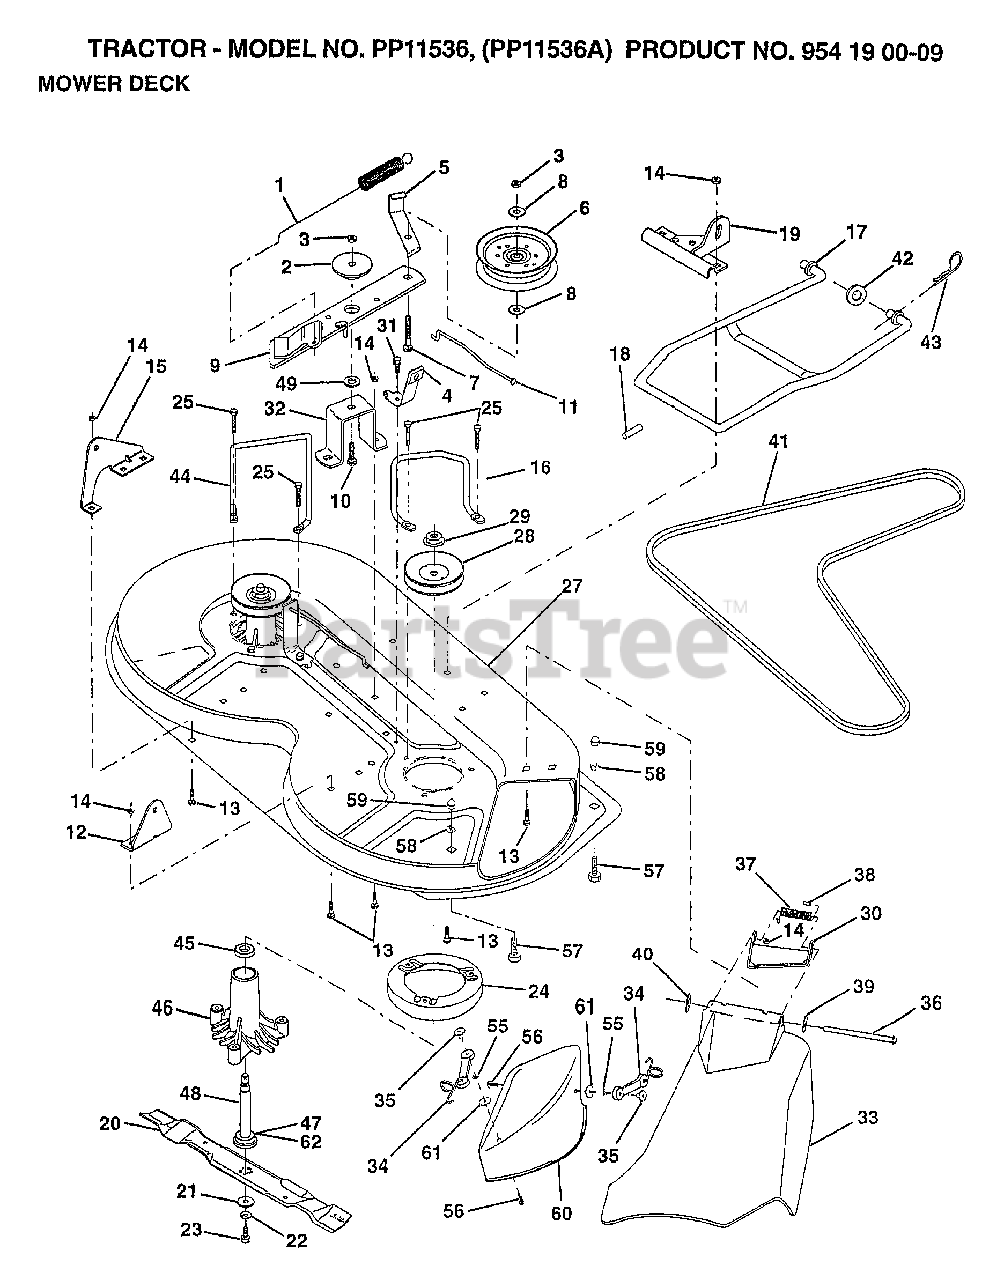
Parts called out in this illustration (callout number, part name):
1	SPRING CLUTCH MWR
2	SPACER RETAINER
4	BRAKE ASM
5	IDLER BELT GUIDE
6	PULLEY IDLER
7	BOLT
8	WASHER
10	BOLT.3/8-14X1.25
11	BRAKE ROD
12	"BRKT,LIFT REAR"
13	BOLT
15	"BRKT,LIFT REAR LH"
16	"KEEPER-BELT,RH"
17	MOWER LINK STAB
18	"PIN,GROOVE"
19	"BRKT,LINK STABILI"
20	"BLADE MULCH 36"""
21	WASHER.HARD.BLADE
23	BLADE BOLT
24	STRIPPER RND MWR
27	"HOUSING-MOWER,36"""
28	PULLEY.MAND.36/46
31	SCREW LT
32	"SUPT,IDLER ARM"
35	NUT, WELD .327-.304 # 10-24
36	HINGE ROD
37	SPRING TORSION
38	CAP-SLEEVE LT
39	WASHER
40	NUT PUSH M
41	V-BELT.PRIM.78.5.
43	RETAINER.SPRING
44	KEEPER BELT LH
45	BEARING
46	HSG ASM MANDREL
47	BEARING.BALL
49	HARDENED WASHER
55	LOCKWASHER
56	SCREW
59	ACORN NUT
60	COVER, MULCHING 36
61	WASHER #10
62	WASHER.FELT.
